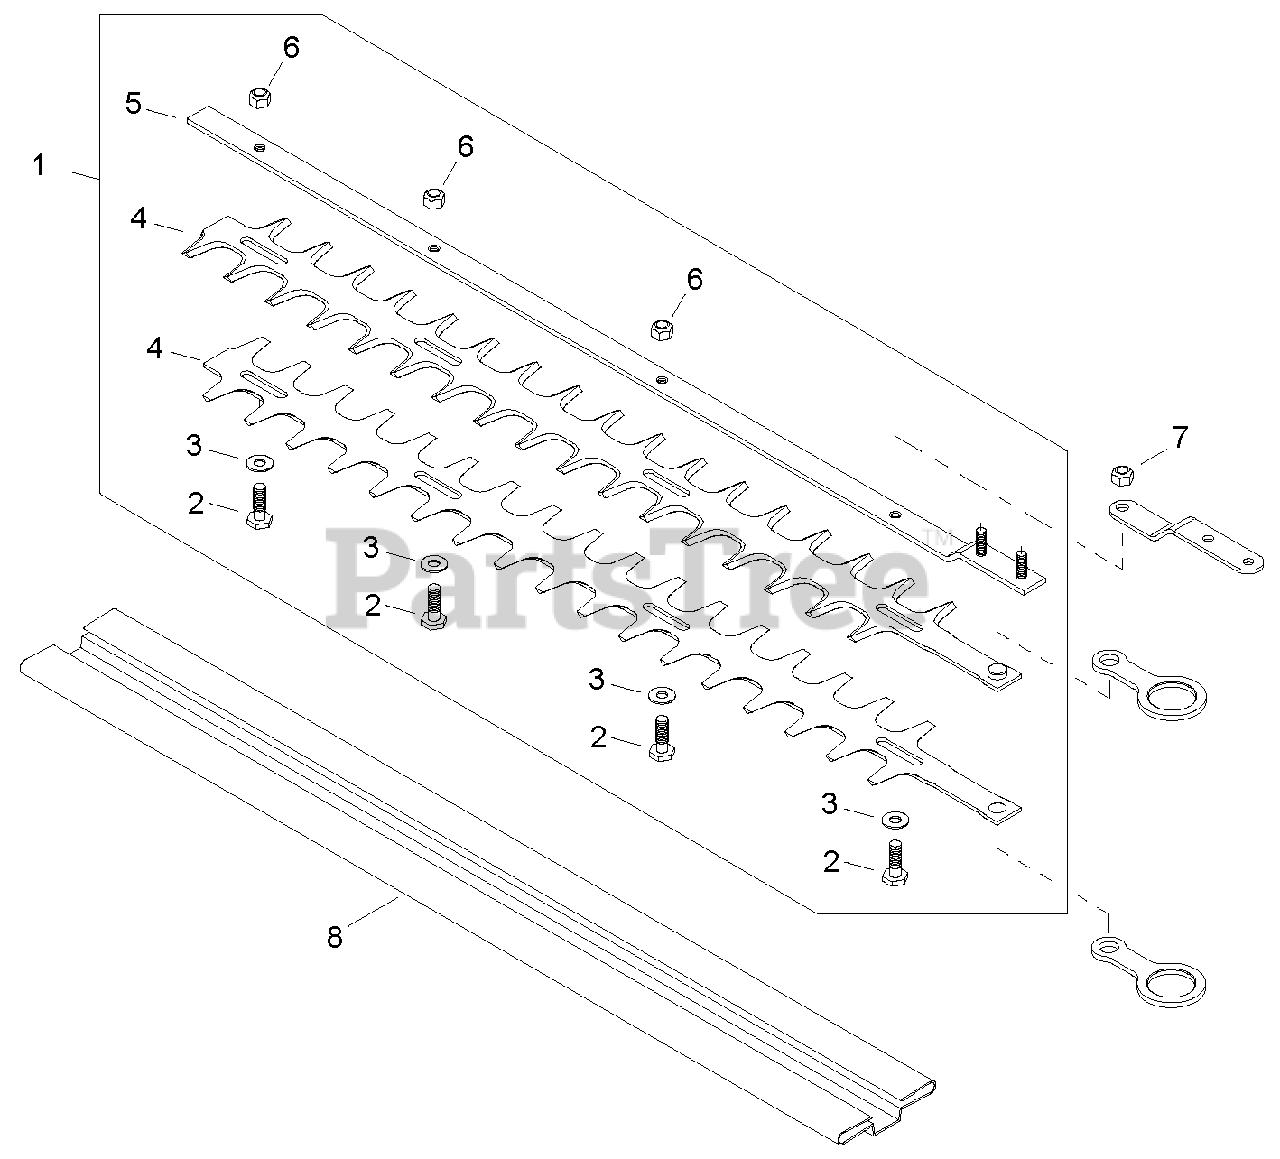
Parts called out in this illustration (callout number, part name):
2	BOLT
3	WASHER
4	BLADE KIT - 22" (55cm) CHROME
5	GUIDE BAR - 22" (56cm)
6	LOCKNUT - 6
7	LOCKNUT - 6
8	COVER, BLADE
12-1	BLADE KIT - 22" (55cm) CHROME
